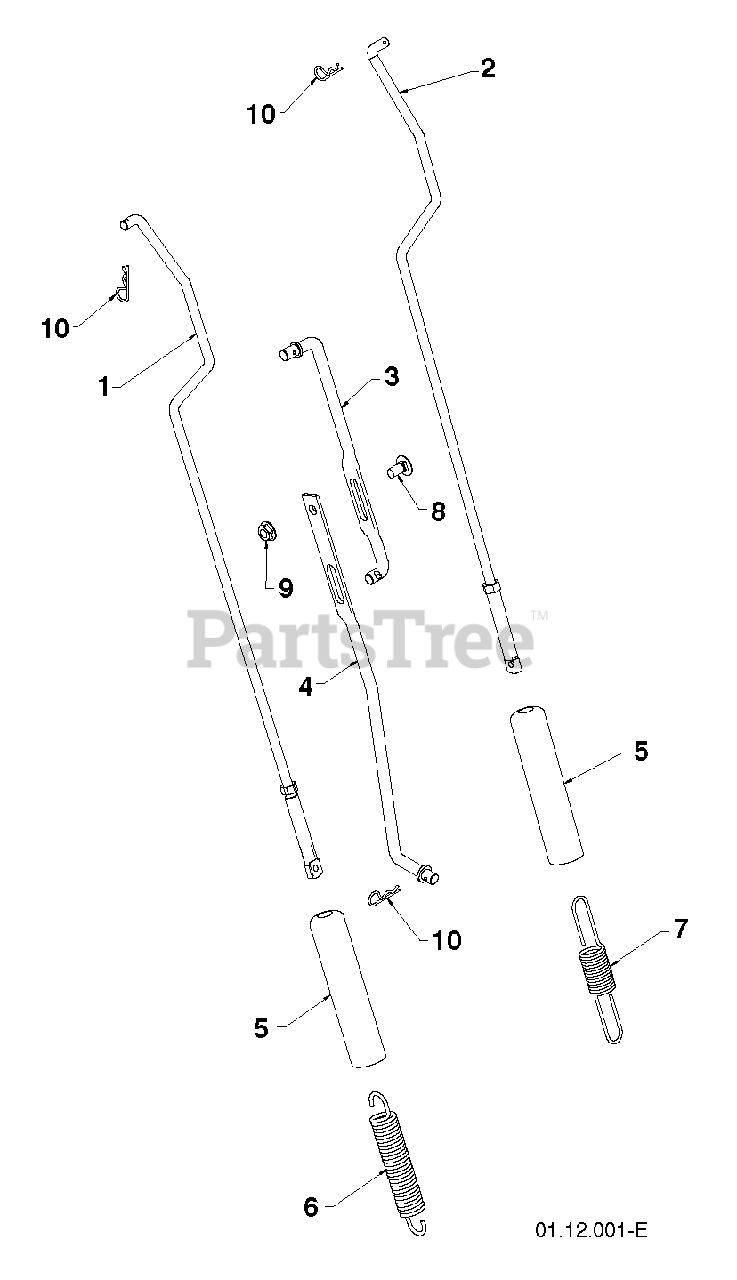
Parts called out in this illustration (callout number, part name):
1	ROD.ASM.IMPELLER
2	ROD.ASM.TRACTION.HYD.CLUTCH
3	ROD.SHIFTER.TOP.HYD
4	ROD, LOWER, SPEED CONTROL
5	SLEEVE, SPRING
6	SPRING, AUGER CONTROL
7	SPRING, TRACTION DRIVE
8	BOLT
9	NUT.FLANGE.5/16
10	SPRING RETAINER
